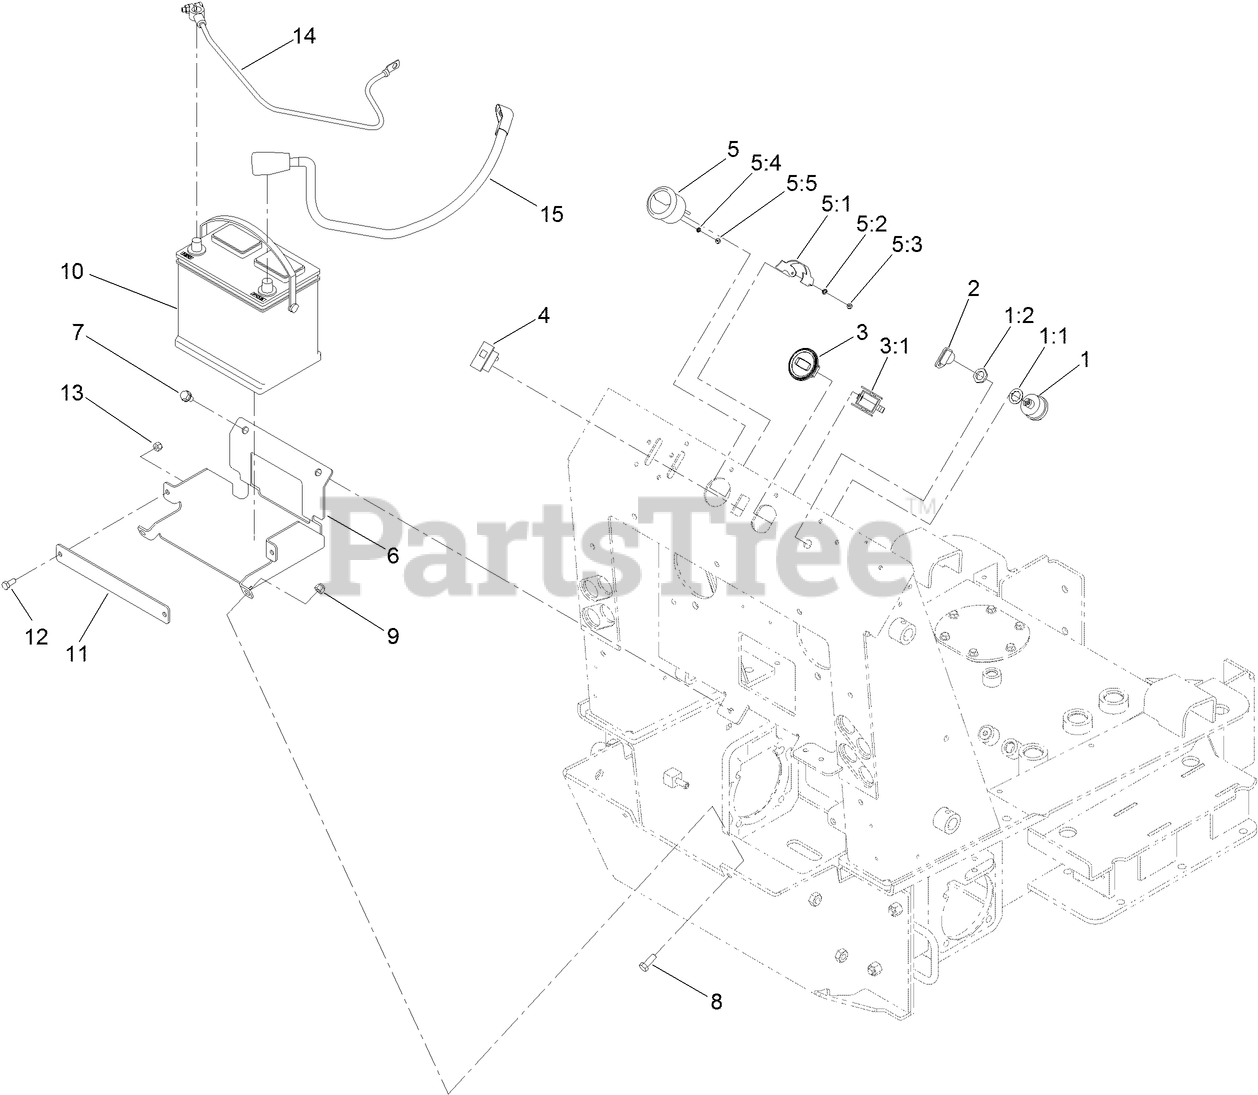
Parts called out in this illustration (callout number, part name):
1	Key Switch ASM
1:1	WASHER-TOOTH, INTERNAL
1:2	NUT-HH
2	KEY-IGNITION
3	INDUCTIVE HOURMETER ASM
3:1	CLIP-MOUNTING
4	LIGHT-TEMP, OIL
5	GAUGE-FUEL
5:1	BRACKET-MOUNTING, GAUGE
5:2	WASHER-LOCK, INT
5:3	NUT-HEX
5:4	WASHER-LOCK / EXT
5:5	NUT-HEX
6	TRAY-MOUNTING, BATTERY
7	SCREW-HWHTF
8	SCREW-HH
9	NUT-LOCK, NI
10	BATTERY
11	CLAMP-BATTERY
12	SCREW-HH
13	NUT-LOCK, NI
14	CABLE-BATTERY, NEGATIVE
15	CABLE-BATTERY, POSITIVE
